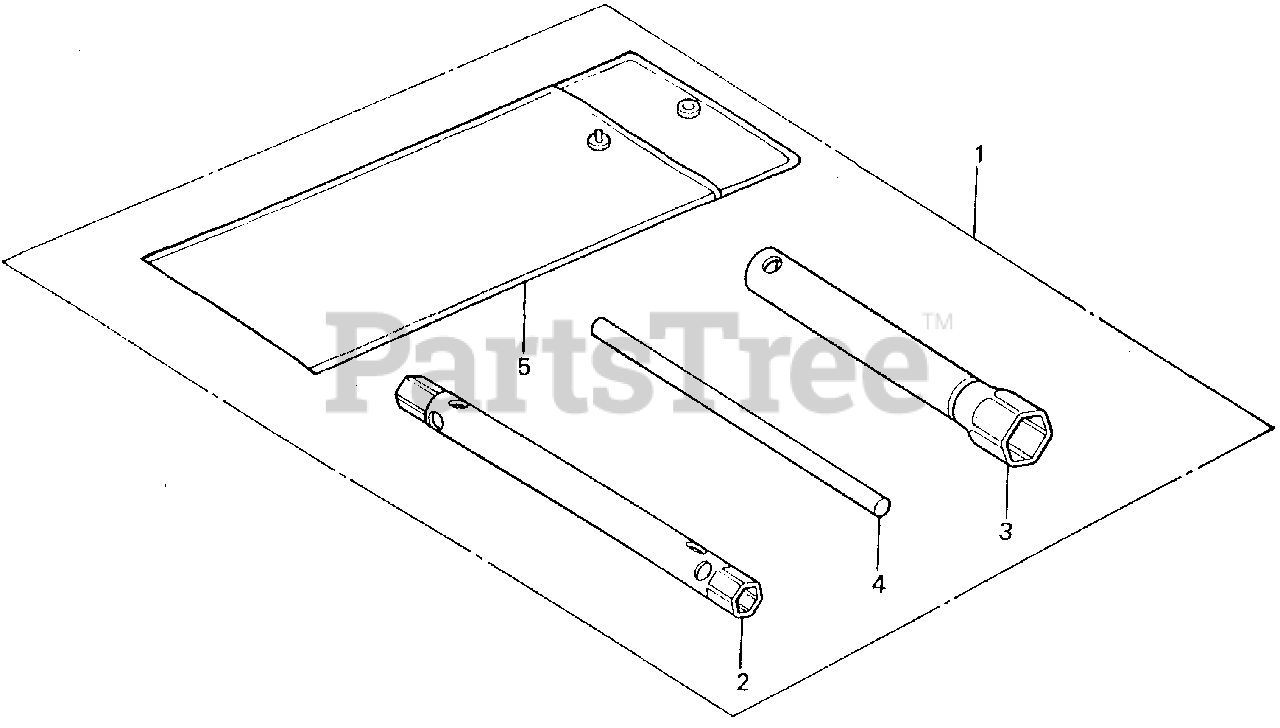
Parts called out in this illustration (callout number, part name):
1	TOOL KIT (NOT AVAILABLE)
2	WRENCH, BOX (10X12) (NOT AVAILABLE)
3	WRENCH, BOX (P21)
4	BAR A, HANDLE
